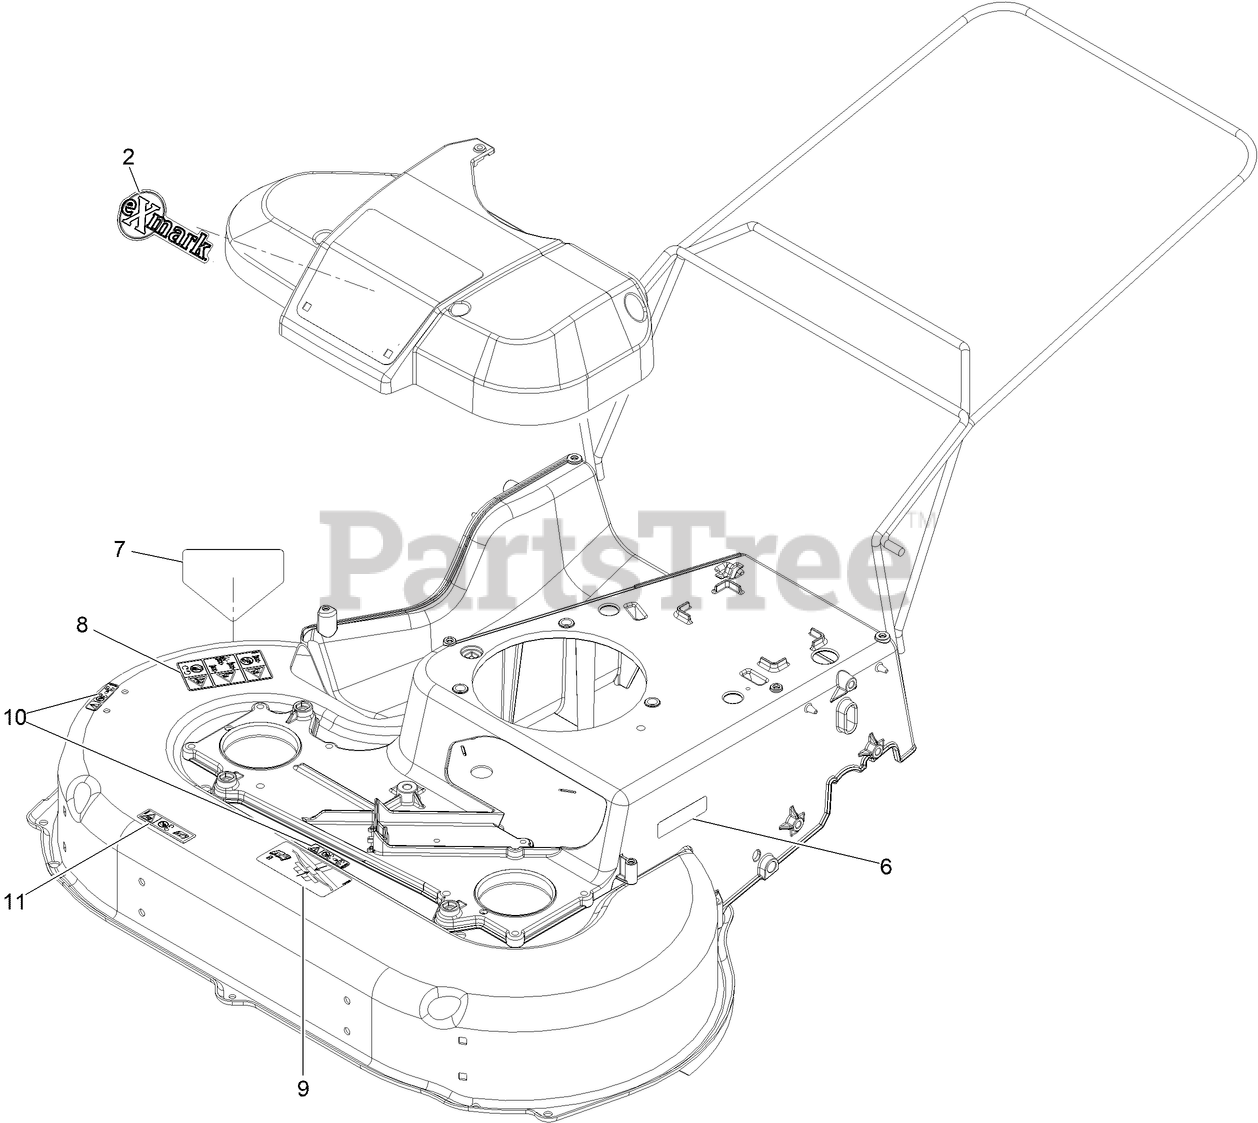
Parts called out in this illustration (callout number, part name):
2	DECAL-EXMARK LOGO
6	DECAL-ARRESTOR, SPARK
7	DECAL-DANGER
8	DECAL-DANGER, CE
10	DECAL-WARNING
11	DECAL-WARNING
